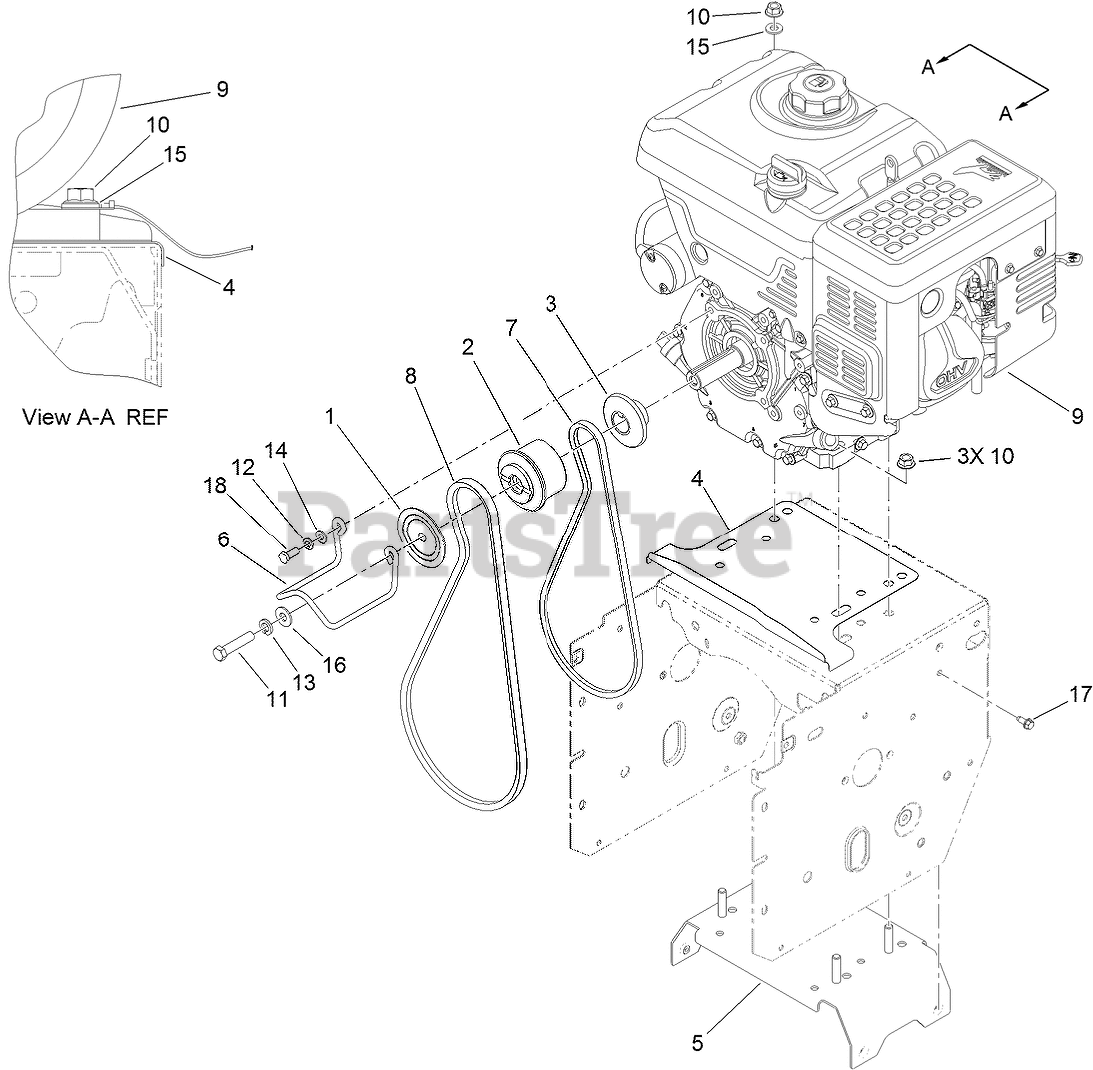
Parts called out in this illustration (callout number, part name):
1	SHEAVE-HALF, IMPELLER
2	PULLEY-ENGINE, CENTER
3	SHEAVE-HALF, TRACTION
4	SHIELD-DRIVE
5	FRAME BRACE ASM
6	GUIDE-BELT
7	BELT-V
8	BELT-V
9	ENGINE-175FDS-1
10	NUT-FLANGE
11	SCREW-HH
12	WASHER-LOCK
13	WASHER-LOCK
14	WASHER-PLAIN
15	WASHER-FLAT
16	WASHER-FLAT
17	SCREW-HWH
18	SCREW-HH
